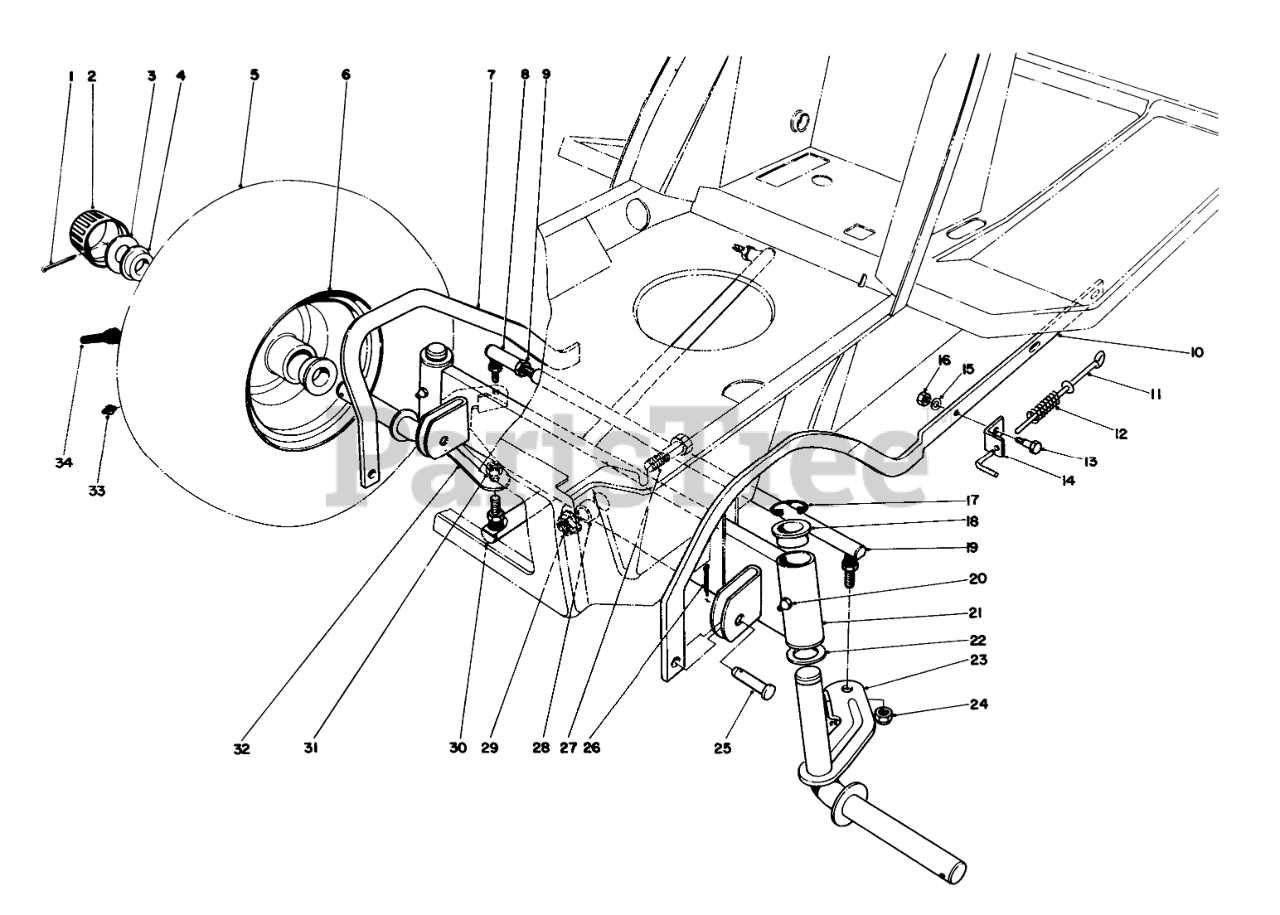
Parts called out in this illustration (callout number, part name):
1	PIN-COTTER
2	Cap-Hub
3	WASHER-PLAIN
4	Bearing
5	FRONT TIRE
6	FRONT RIM
7	Scissors Link-R.H.
8	JOINT-BALL
9	NUT-JAM
10	Scissors Link-L.H.
11	Pin-Tension
12	COMP SPRING
13	Bolt-Shoulder
14	TENSION BELT BRKT B
15	WASHER-PLAIN
16	NUT-LOCK, CONE
17	E-RING
18	BEARING-FLANGE
19	Tie Rod-Steering (Incl. Ref. #8 & 9)
20	GREASE FITTING
21	Front Axle (Incl. Ref. #18)
22	WASHER-THRUST
23	LH SPINDLE WA PP
24	NUT-LOCK, NI
25	PIN-CLEVIS
26	PIN-COTTER
27	SCREW-HH
28	SPACER-AXLE, FRONT
29	NUT-HF
30	STEERING ARM B
31	NUT-HEX
32	RH SPINDLE WA PP
33	FITTING-GREASE
34	STEM-VALVE
